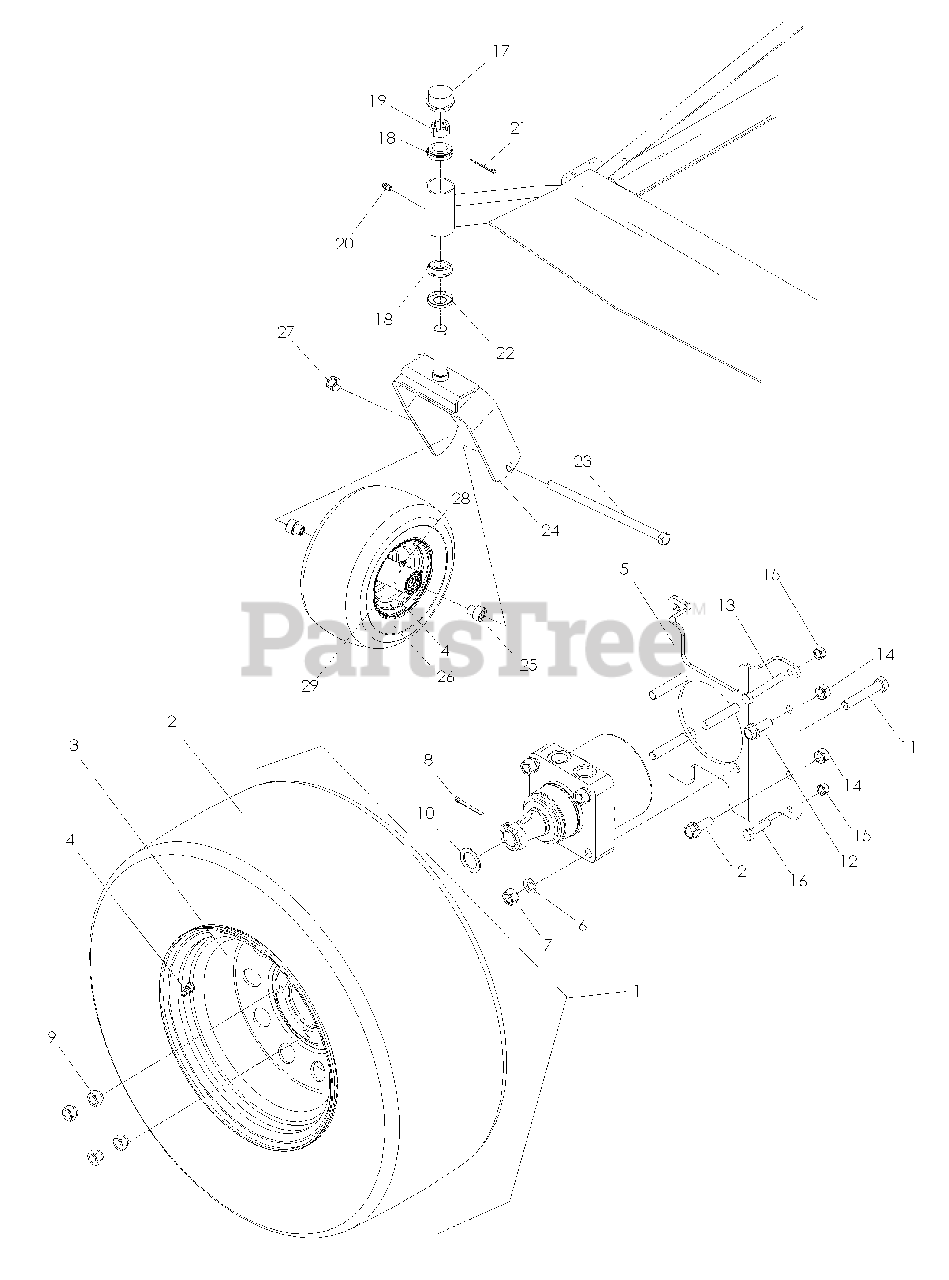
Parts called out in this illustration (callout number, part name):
1	TIRE ASSEM, RR 23 x 9.5-12
3	RIM RR
5	MOUNT WHEEL MOTOR
6	WASHER, 1/2 SPLT LOCK
7	NUT 1/2-13 HEX
8	COTTER PIN
9	LUG NUT 1/2
10	BUSHING, 1 x 14 GA
11	HCS 1/2-13 x 2 3/4
12	BOLT 1/2-13 x 1 1/4 WHIZLK
13	HCS 3/8-16 x 2 1/4
14	NUT 1/2-13 HEX
15	NUT 3/8-16 HEX NYLOC
16	HCS 3/8-16 x 1 1/4
17	CAP GREASE
18	BEARING-ROLLER
19	NUT 1-14 SLOTTED JAM
21	COTTER PIN
23	HCS 1/2-13 x 9 1/2
24	YOKE, CASTER
25	SPACER, AXLE
26	WHEEL ASSEM, CASTER
27	NUT 1/2-13 HEX NYLOC
28	ZERK
